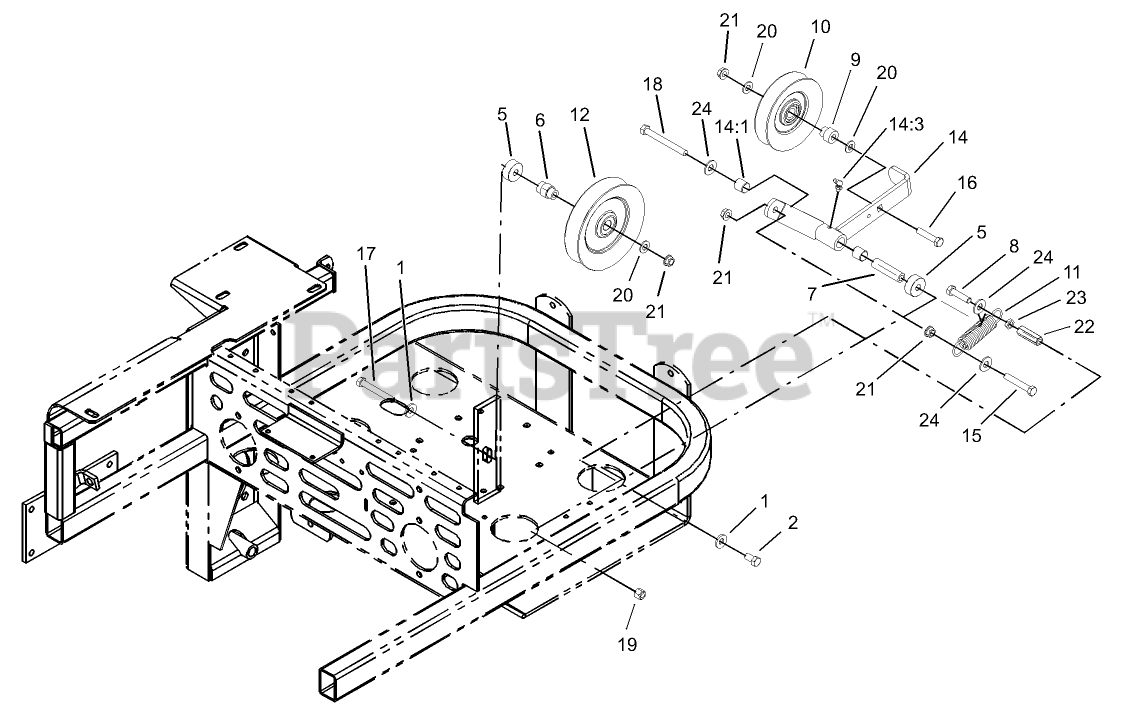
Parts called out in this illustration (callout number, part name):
1	WASHER-BELLEVILLE
2	SCREW-HH
5	Spacer-Idler
6	Spacer (only on: 74236)
6	Bushing-Idler (only on: 74213)
7	BUSHING-PIVOT, IDLER
8	SCREW-HH
9	Bushing-Idler (only on: 74236)
9	Bushing-Idler (only on: 74213)
10	Idler
11	SPRING-EXTENSION
12	PULLEY-IDLER
14	IDLER ARM ASM
14:1	SLEEVE-BEARING
14:3	FITTING-GREASE, 90 DEG
15	SCREW-HH
16	SCREW-HH
17	SCREW-HH
18	SCREW-HH
19	NUT-LOCK, NI
20	WASHER-FLAT
21	NUT-HHF, WHIZ
22	Nut-Coupling
23	NUT-JAM
24	WASHER-FLAT
